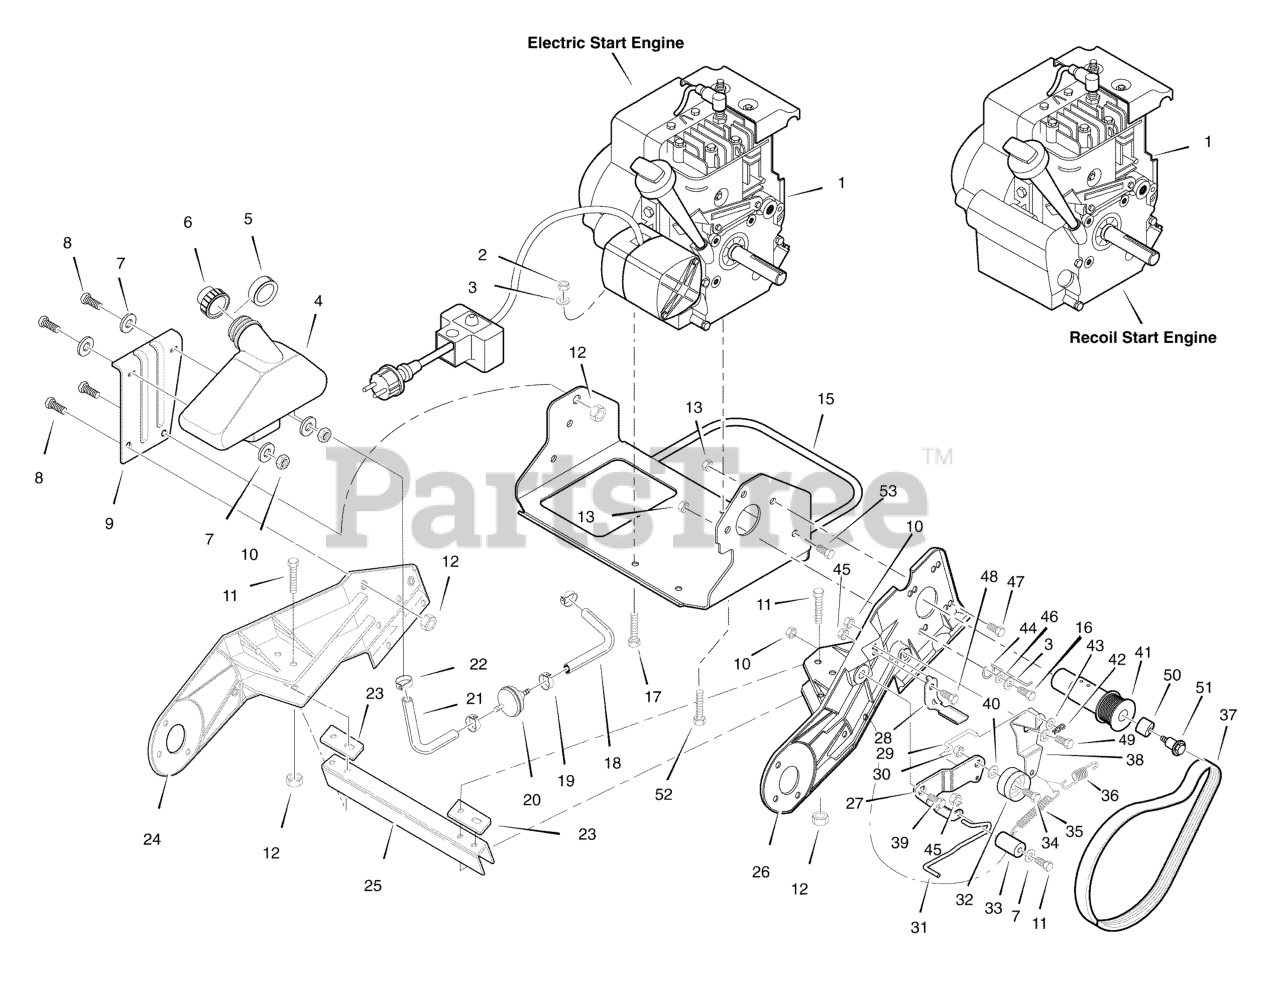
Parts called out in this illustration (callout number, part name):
1	ENGINE
2	NUT, 5/16-18
3	WASHER, SPLIT LOCK .31 X .58 X .08
4	TANK, FUEL 1.5 QT
5	RING, FOAM FUEL TANK
6	FUEL CAP
7	WASHER, FLAT .281 X .63. X .065
8	SCREW, 1/4-20 X 0.75
9	BRACKET, FUEL TANK
10	NUT, 8-32 HEX KEPS
11	SCREW, 1/4-20 X 2.00
12	NUT, 1/4-20 HEX
13	NUT, 5/16-18 HEX CONTROL LOCK
15	CRADLE, WELDMENT
16	BOLT, 5/16-18 X 0.75
17	BOLT, HEX .31-18 X 1.62
18	HOSE, FUEL 12 INCHES
19	CLAMP, HOSE
20	FILTER- FUEL
21	HOSE, FUEL 12 INCHES
22	CLAMP, SCREW TYPE
23	PLATE, SUPPORT
24	FRAME, RIGHT HAND
25	CHANNEL, FRAME SUPPORT
26	FRAME, LEFT HAND
27	ARM, IDLER BLACK
28	BRAKE PAD
29	ROD, CLUTCH LINKAGE
30	NUT, 3/8-16 JAM CONTROL LOCK
31	WIRE, BRAKE
32	PULLEY, IDLER
33	PINCH ROLLER
34	SCREW, 3/8-16 X 1.50
35	SPRING, EXTENSION .38 O.D. X .039 X 2.50
36	SPRING, EXTENSION .75 O.D. X .069 X 2.00
38	ARM, IDLER PIVOT
39	BOLT, SHOULDER .500 X .177
40	WASHER, FLAT .378 X .75 X .080
41	PULLEY, ENGINE
42	PIN, COTTER
43	WASHER, FLAT
44	GUIDE, BELT
45	NUT, 1/4-20 HEX CONTROL LOCK
46	WASHER, FLAT .349 X .69 X .066
47	SCREW 5/16-18 X 0.63 WAHHC
48	SCREW, 1/4-20 X 0.63
49	SCREW, 8-32 X 3.00
50	SPACER, DRIVE PULLEY
51	BOLT, ENGINE PULLEY, 1/4-28 X 1.28
52	BOLT, 5/16-18 X 0.865
53	SCREW, .25-20 X .062 WASHER HEX HEAD TAPTITE
